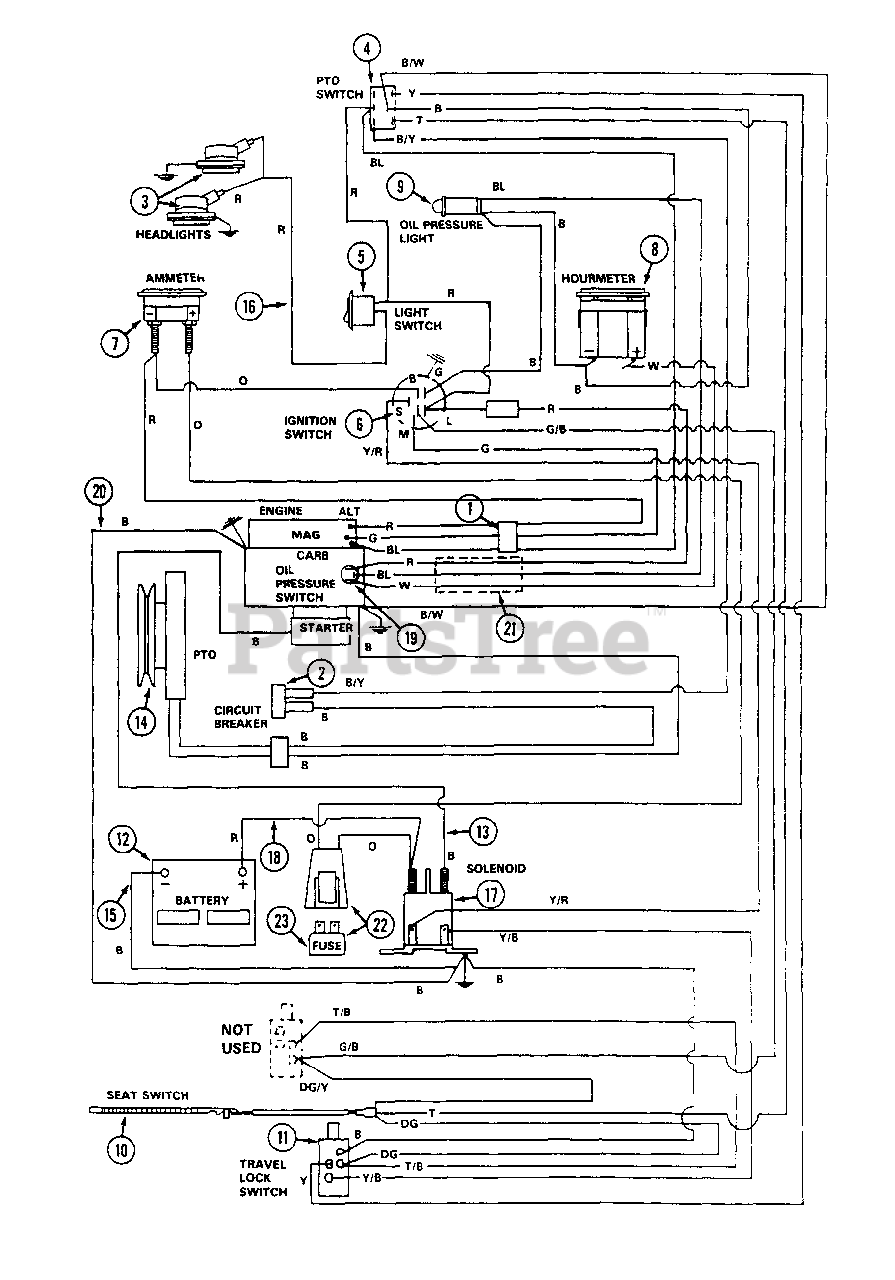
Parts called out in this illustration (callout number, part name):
1	HARNESS - wire, alternator and magneto
2	BREAKER - circuit, 10 amp
4	SWITCH - PTO
5	SWITCH - headlight
6	SWITCH - ignition
8	METER - hour
10	SWITCH - seat
11	SWITCH - safety
12	BATTERY - 12 volt
13	WIRE - starter
15	CABLE - ground
16	WIRE - headlight
17	SOLENOID - start
18	CABLE - battery positive to solenoid
19	SWITCH - oil light
20	WIRE - ground
21	HARNESS - oil pressure switch
22	KIT - fuse holder
23	FUSE - 30 amp
